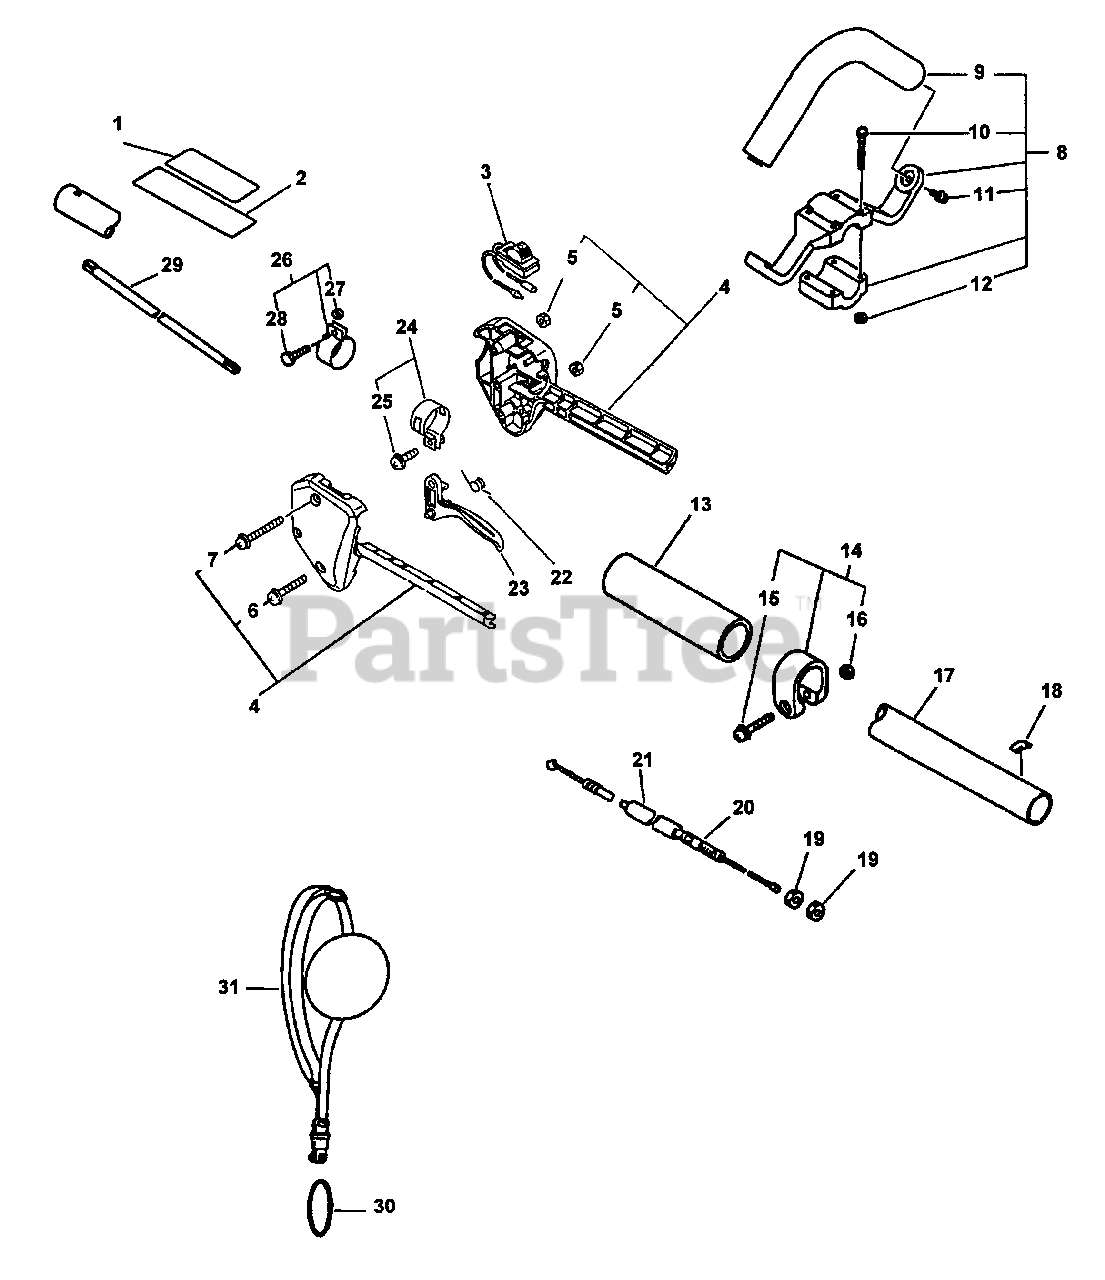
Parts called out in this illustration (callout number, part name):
1	LABEL, CAUTION
2	LABEL, CAUTION
3	SWITCH, ON-OFF
4	HANDLE KIT, CONTROL
5	NUT M5
6	SCREW 5×25
7	SCREW 5×35
8	LOOP HANDLE ASSY
9	HANDLE
10	SCREW 5×35
11	SCREW 5×14
12	NUT M5
13	GRIP, HANDLE
14	CLAMP KIT
15	SCREW 5×28
16	NUT M5
17	MAIN PIPE ASSY 25×L= 1500
18	LABEL - ALIGNMENT
20	CABLE, THROTTLE
21	TUBE - VINYL
22	SPRING, TORSION
23	TRIGGER, THROTTLE
24	CLAMP KIT
25	SCREW 5×12
26	HOOK
27	SPACER, GUARD
28	BOLT 5×18
29	DRIVESHAFT
30	RING, HARNESS Ø32
31	SHOULDER STRAP ASSY
